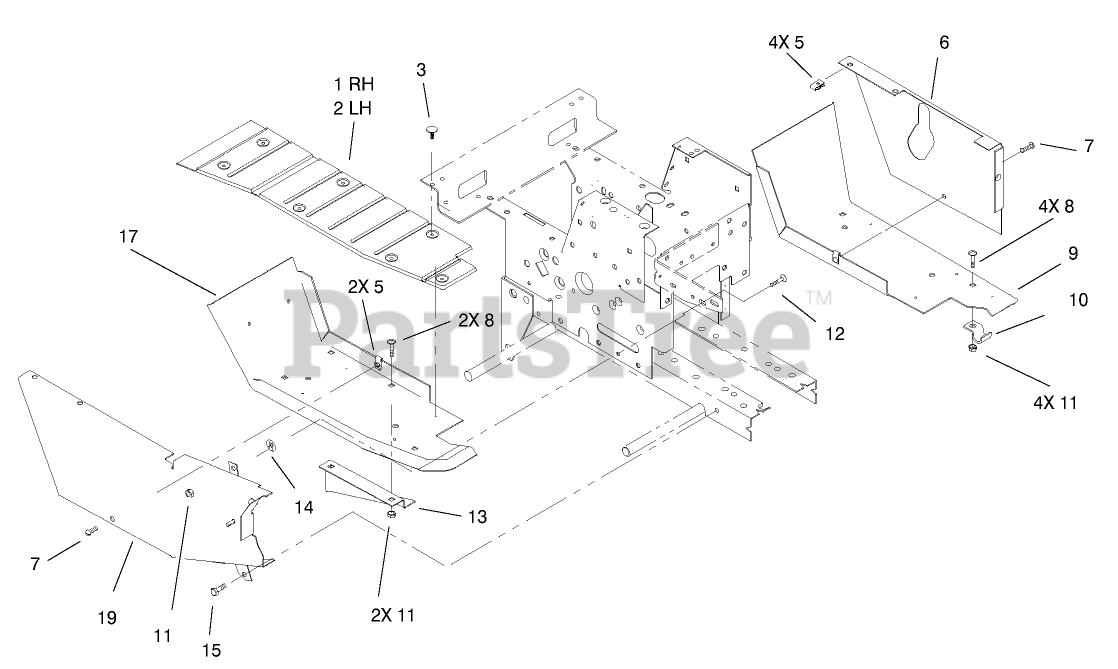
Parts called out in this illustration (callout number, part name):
1	PAD-FOOT RH
2	PAD-FOOT LH
3	FASTENER-PANEL
6	COVER-LH
7	SCREW-PPH
8	BOLT-CARR
9	FOOTREST-LH
10	BRACKET
11	NUT-LOCK, NI
12	BOLT-CARR
13	GUIDE-LOWER BELT
15	SCREW-HWHTF
17	FOOTREST-RH
